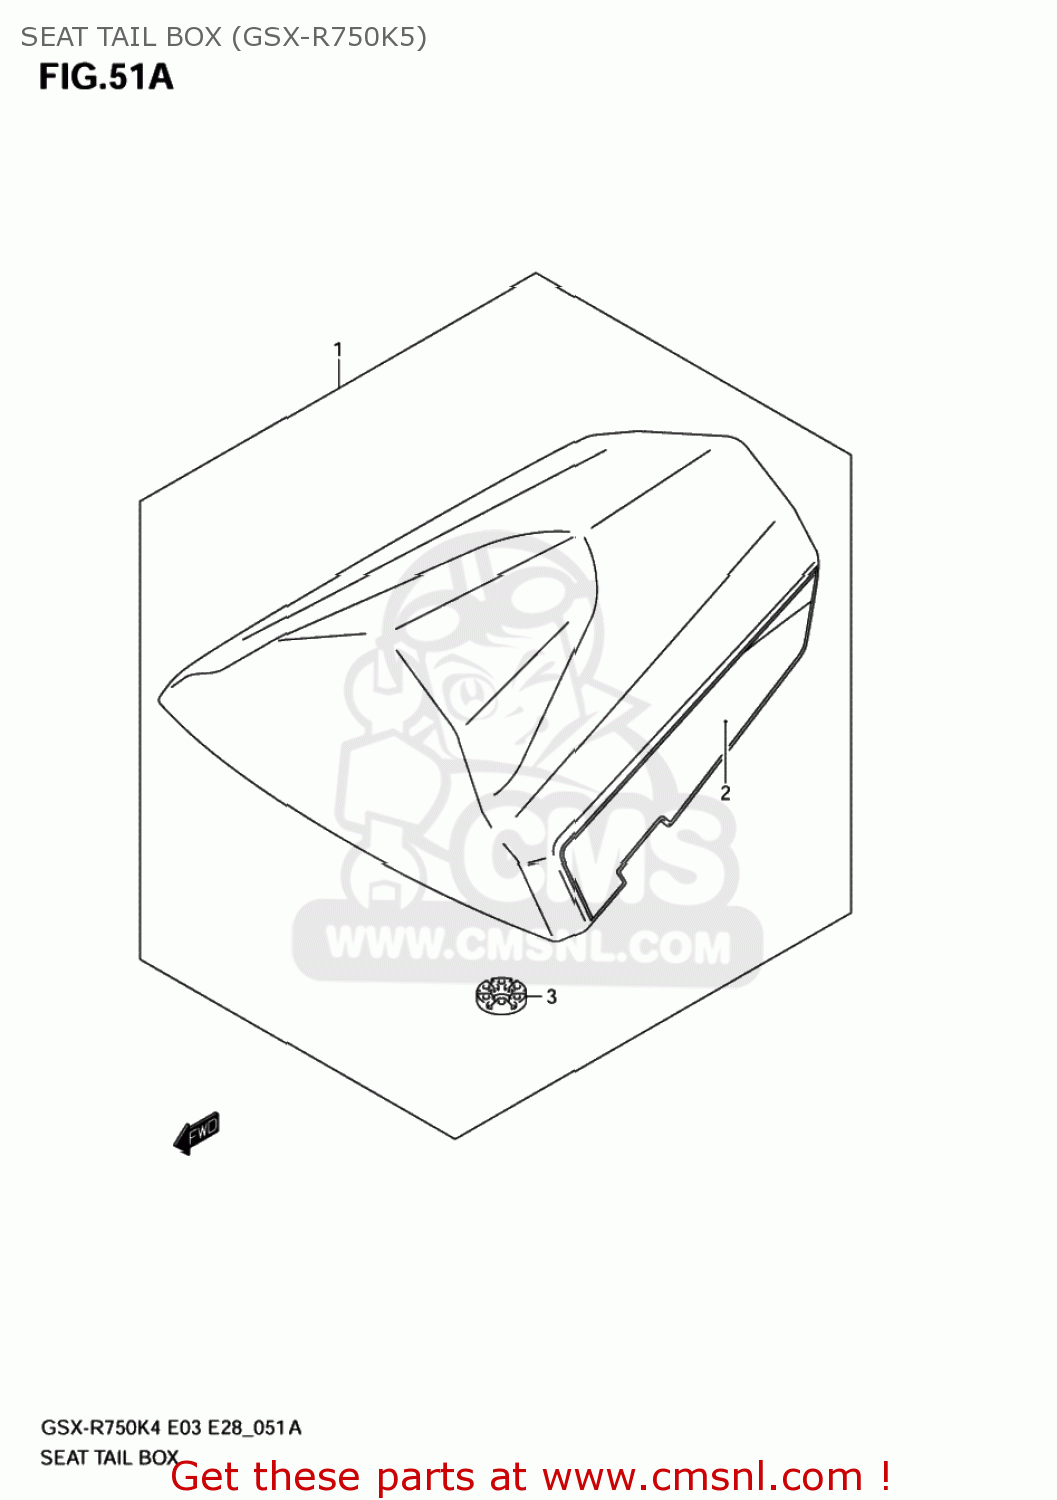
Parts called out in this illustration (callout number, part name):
1	BOX ASSY,SEAT TAIL(BLUE)
2	TAPE SET,BOX SEAT TAIL
3	CUSHION
